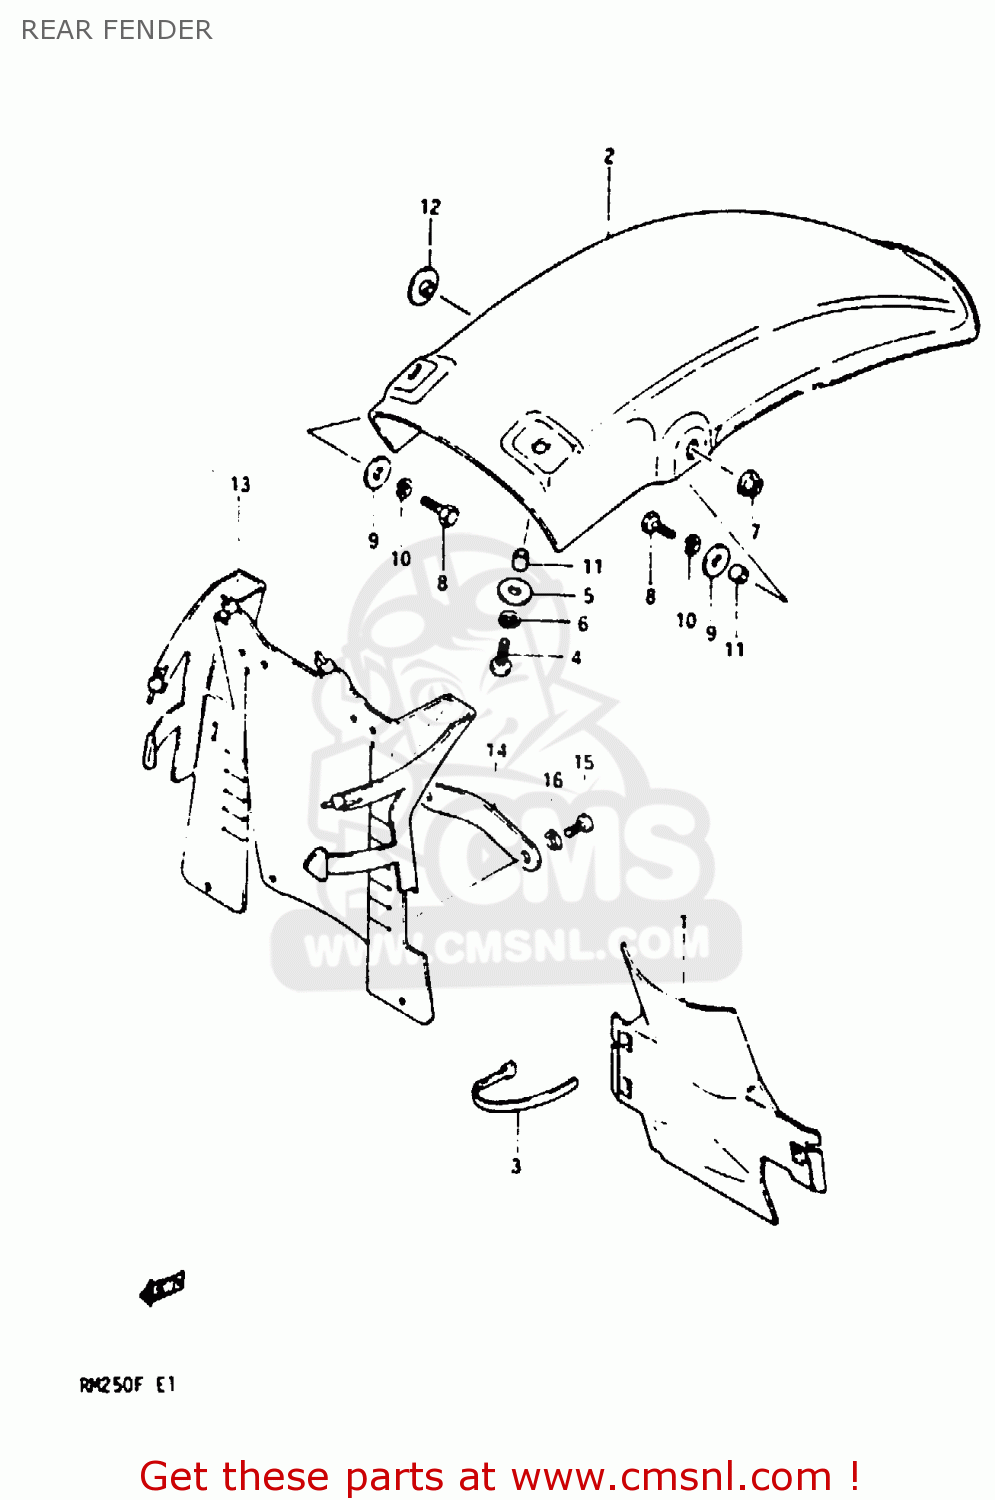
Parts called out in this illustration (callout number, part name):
1	FENDER,FRONT,REAR
2	FENDER,REAR
3	CLAMP
4	SCREW
5	WASHER
6	LOCK WASHER
7	NUT
8	BOLT
9	WASHER (6.5X20X1.2)
10	LOCK WASHER
11	SPACER
12	WASHER
13	GUARD,REAR FENDER MUD
14	PLATE,MUD GUARD
15	SCREW
16	WASHER,5MM
